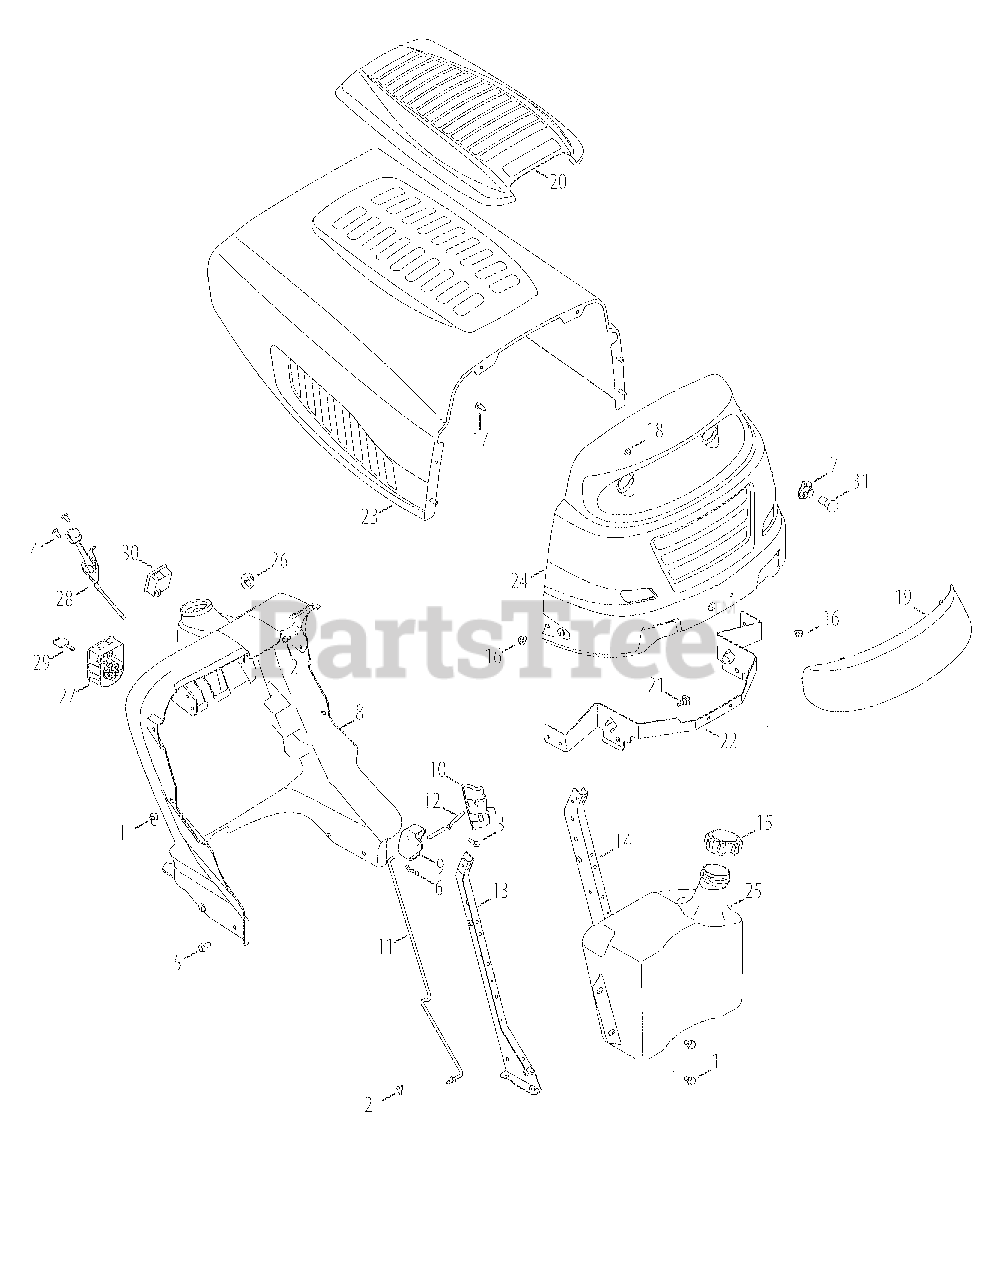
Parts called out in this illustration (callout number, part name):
1	Taptite Screw ,5/16-18:.750
2	Taptite Screw ,1/4-20:0.500
3	Hi-Lo Screw, 1/4-15:0.750
4	Screw, 1/4-14:0.625
5	Taptite Screw, 5/16-18:0.750
6	Bow Tie Cotter Pin
7	Lamp Socket
8	Dash Panel
9	Dash Lever
10	Cruise Cover
11	Control Rod
12	Lever
13	RH Support Plate
14	LH Support Plate
15	Fuel Cap
16	Taptite Screw ,5/16-18:0.375
17	Hex Screw, 1/4-20:.620
18	Flangelock Nut, 1/4-20
19	Grill Lens
20	Hood Scoop
21	Shoulder Screw, .43X.29:5/16-18
22	Hood Pivot Bracket
24	Grill
25	Fuel Tank
26	Choke Plug
27	Key Switch Module
28	Throttle/Choke Cable
30	Hour Meter
